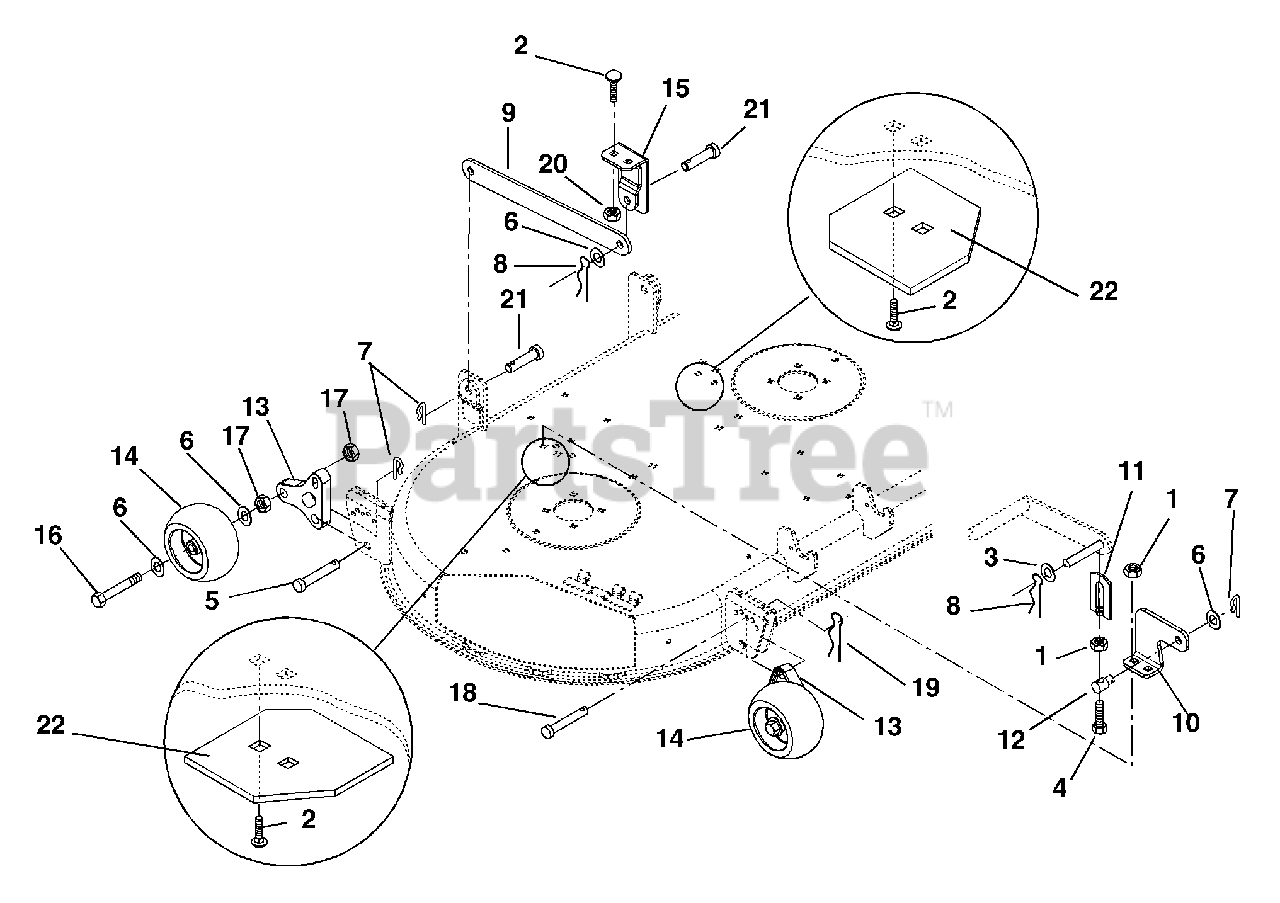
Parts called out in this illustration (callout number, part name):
1	Nut-Locking-Center .38-16
2	Bolt Round Head Square Neck .38-16
3	Washer-Flat-Steel .563 x 1.38 x .109
4	Bolt-Hex .38-16 x 2.50 Grade 5
5	Pin-Clevis .50 x 1.38
6	Washer-Flat-Steel .505 x .88 x .072
7	Clip-Spring
8	Pin-Hair-External .12 x .31 x 2.37
9	Link-Lift
10	Bracket-Lift
11	Link-Adjustment
12	Trunnion
13	Bracket-Roller Bracket Adjustment
14	Wheel 5" x 3"
15	Weldment-Deck Stop Bracket
16	Bolt-Hex .50-13 x 4.00
17	Nut-Locking-Center-Jam .50-13
18	Pin-Clevis .31 x 1.38
19	Pin-Hair Internal .08 x .18 x 1.18
20	Nut-Locking-Nylon .38-16
21	Pin-Clevis .50 x 1.00
22	Reforcement, Deck Lift
